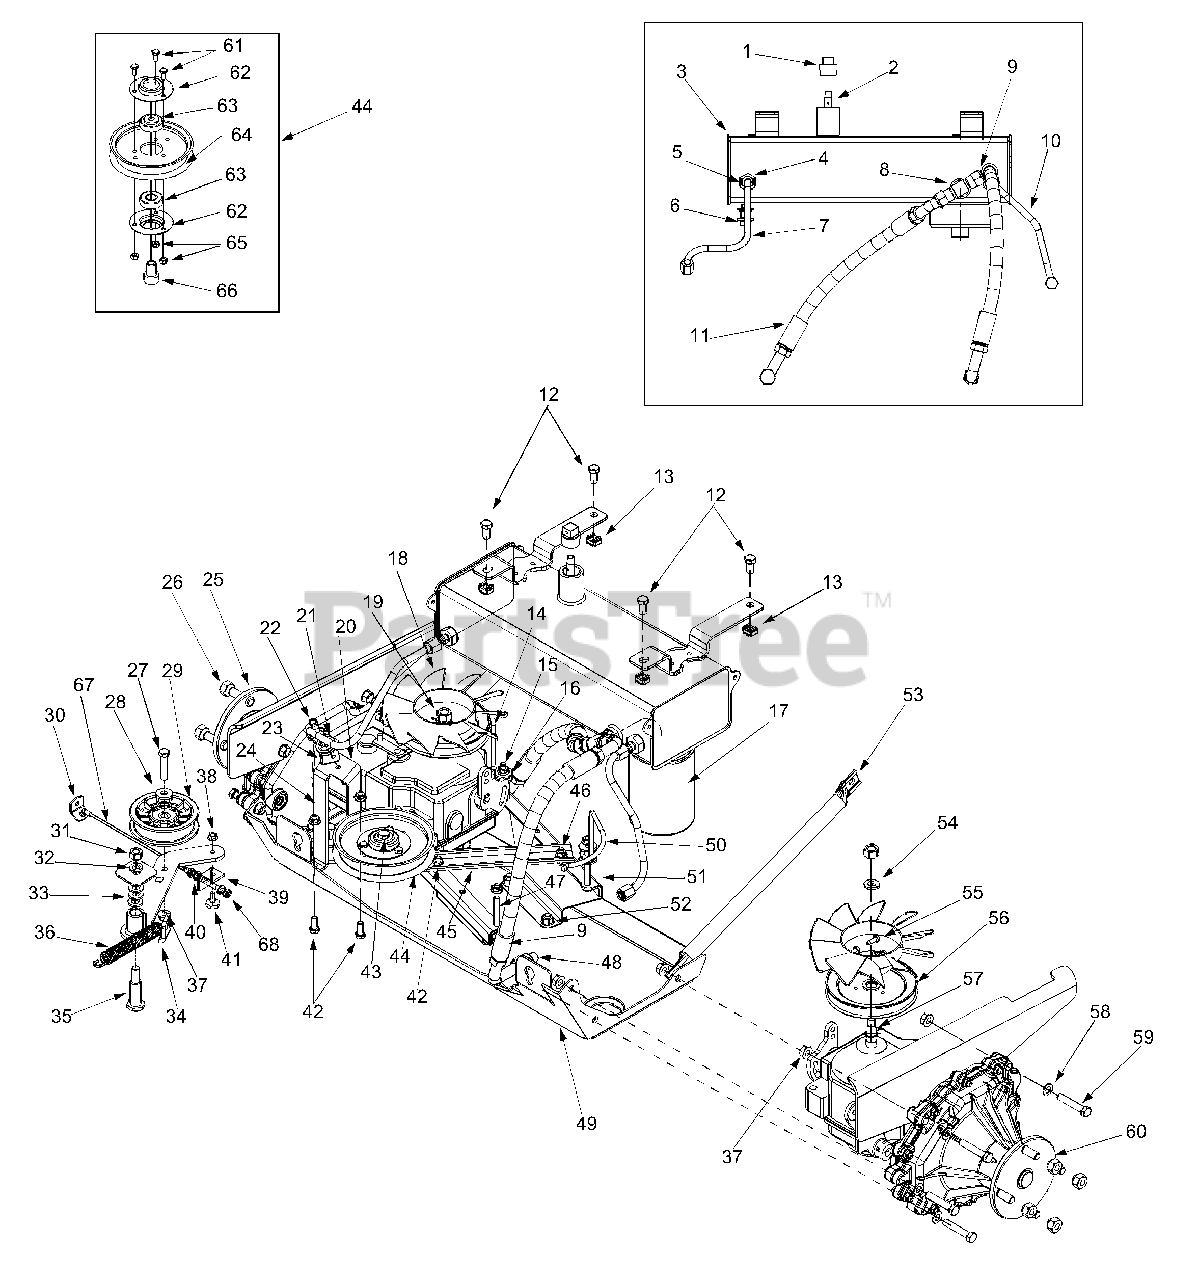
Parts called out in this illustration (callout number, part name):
1	Pipe Plug
2	Pipe Dipstick
5	Seal
6	Drain Plug
7	Inlet Tube LH
8	Tee Fitting
9	Outlet Hose RH
10	Inlet Tube RH
11	Outlet Hose LH
12	Hex Cap Screw 3/8-16 x .75
13	Retainer Nut 3/8-16
14	Belt Retainer Rod RH
15	Hex Cap Screw 5/16-18 x 2.5
16	Flat Washer 5/16
17	Filter Element
18	Fan Blade
19	Hex Nut 1/2-20
20	Mounting Pulley Bracket
21	Roller Cable
22	Hex Shoulder Screw 1/4-28 x .375
23	Retainer Cable Bracket
24	Lock Nut 1/4-28
25	Complete Transmission Assembly LH
27	Hex Cap Screw 3/8-16 x 1.75
28	Flat Washer .385 ID x 1.0 OD
29	Flat Idler Pulley 3.5 OD
30	Mounting Bracket Cable
31	Hex Nut 7/16-14
32	Lock Washer 7/16
33	Flat Washer .469 ID x .875 OD
36	Extension Spring 6.12 Lg
37	Flange Lock Nut 3/8-16
38	Lock Nut 1/4-20
40	Lock Washer 5/16
41	Shoulder Screw
42	Hex Cap Screw 5/16-18 x .75
43	Hex Cap Screw 3/8-16 x 2.25
44	Idler Pulley Assembly 5.0"
47	Hex Cap Screw 5/16-18 x 2.0
48	Connection Fitting 1/2 x 3/8
55	Hex Washer Screw #12-24 x .625
56	Transmission Pulley
57	Wire Ring
58	Flat Washer
59	Hex Cap Screw 3/8-16 x 2.0
60	Complete Transmission Assembly RH
61	Hex Cap Screw 1/4-20 x .62
62	Bearing Cup
63	Ball Bearing
64	Idler Pulley 5.0"
65	Hex Lock Nut 1/4-20
66	Idler Spacer
67	Declutching Cable
68	Jam Nut 5/16-18
